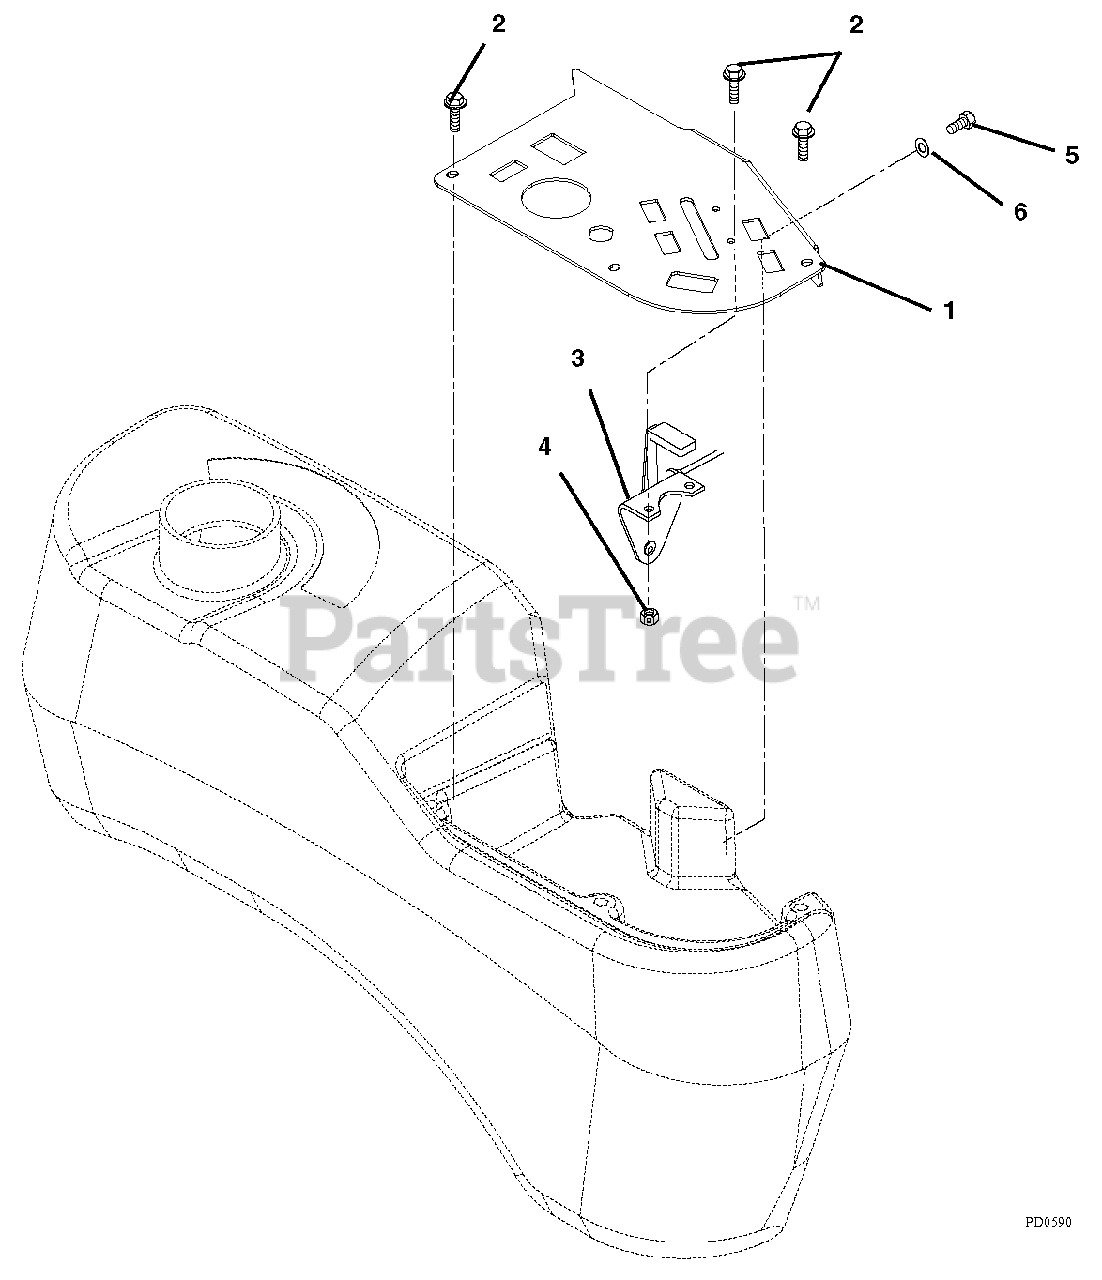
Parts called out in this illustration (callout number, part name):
1	Panel, Control
2	Screw, Machine 10-24 x .50 Hex Washer Head Stainless
3	Throttle, Control
4	Nut, Locking Nylon 10-24 With Insert
5	Bolt, Hex .31-18 x .75 Grade 5
6	Washer, Flat Steel .38 x .875 x .083
